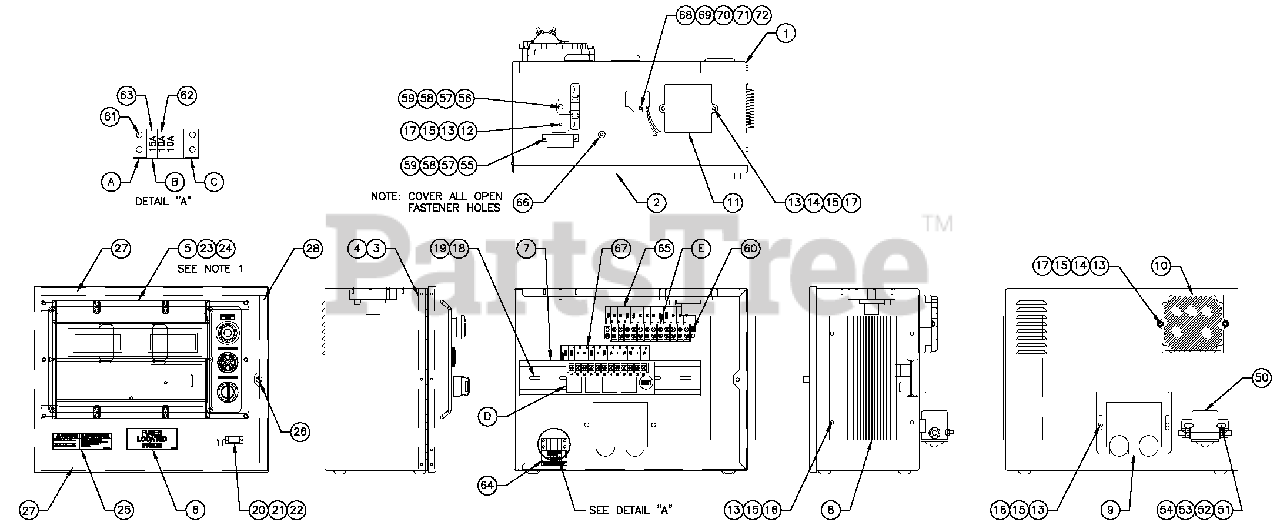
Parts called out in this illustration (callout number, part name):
1	ENCLH/G CONTROL PANEL
2	COVER CONTROL PANEL
3	HINGE CONTINUOUS H PANEL
4	RIVET POP .125X.275SS
5	ASSY PROGRAMMED H-100
6	DECAL FUSES LOCATED INSIDE
7	RAIL SNAPTRACK PCB HOLDER BULK
8	ASSY PCB 10A UL BATT CHRGR12V
9	PLATE HARNESS CLAMP
10	ASSY PCB PWR AVRW/AMP HEADER
11	ASSY PCB BOSCH GOV DRIVER
12	DIO BRIDGE 25A 600V
13	WASHER LOCK M5
14	SCREW PPHM M5-0.8X 30 SS
15	WASHER FLAT M5
16	SCREW HHPM M5-0.8X 12
17	NUT HEX M5-0.8 G8 YEL CHR
18	WASHER FLAT M4
19	SCREW PHTT M4-0.7 X 10 ZYC
20	CONN DUST CAP W/CHAIN DB9
21	WASHER FLAT M3.5
22	SCREW PHTT M3.5-0.6 X 10
23	SCREW PPHM M4-0.7 X 8 BLX OX
24	WASHER LOCK #8-M4
25	DECAL WRN BATT CHRG 12/24V BI
26	M5-0.8 CAPTIVE PANEL KNLD HD
27	SEAL COVER 3.18 X 12.7 X 382
28	SEAL COVER 3.18 X 12.7 X 283
50	RELAY CONTACTOR 12VDC
51	SCREW HHC 1/4-20 X 3/4 G5
52	WASHER FLAT M 6 -1/4
53	WASHER LOCK M6-1/4
54	NUT HEX 1/4-20 STEEL
55	CIRCT BRK 7 X 1 ETA 46-500-P
56	RES WW 15R 5% 25W QK CONN
57	WASHER LOCK M3
58	NUT HEX M3-0.5 G8 YEL CHR
59	WASHER FLAT M3
60	SCREW PHTT #6-32 X 5/8 ZYC
61	SCREW PHTT #6-32 X 3/8 ZYC
62	FUSE ATO TYPE 10 AMP (RED)
63	FUSE ATO TYPE 15 AMP (BLUE)
64	DECAL CPL CONTROL PANEL FUSES
65	DECAL CPL 5.4/6.8L TB3
66	SEAL WEATHER .45" DIA
67	DECAL CPL 5.4/6.8L RELAY BOARD
68	ASSY PCB CAM TO DIST SENSOR
69	SCREW PPHM M5-0.8 X 12 ZNC
70	WASHER FLAT M5
71	WASHER LOCK M5
72	NUT HEX M5-0.8 G8 CLEAR ZINC
A	ADPTR RH SIDE WICKMANN 178.6191
B	HOLDER FUSE WICKMANN 178.6150
C	ADPTR LH SIDE WICKMANN 178.6192
D	ASSY PCB G-PANEL RELAY 12VDC
E	BLOCK TERM 20A 12 X 6 X 1100V
